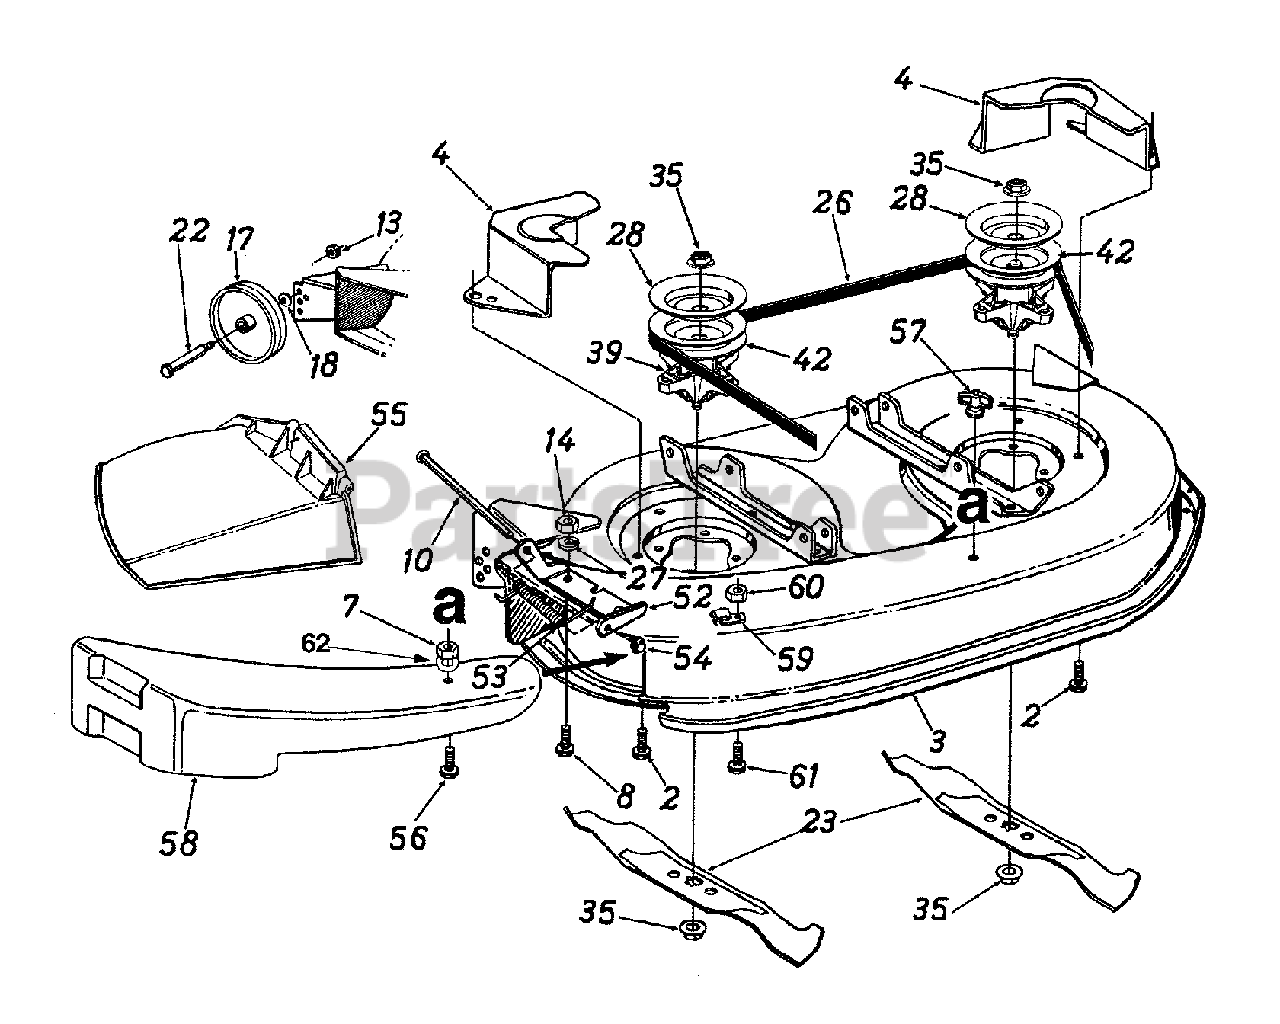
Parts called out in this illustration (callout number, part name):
2	Hex Wash. TT-Tap Scr. 5/16-18 x .75"
7	Hex Lock Nut 1/4-20 Thd.
8	Hex Bolt 1/4-20 x .62"
10	Hinge Pin
13	Hex Top Lock Nut 3/8-16 Thd.
14	Hex Nut 1/4-20 Thd. (Gr. 5)
17	Deck Wheel- 5"
18	BelLock Washer .40" I.D. x .88" O.D.
22	Shld. Bolt .498" Dia. x 1.53"
23	3 in 1 Blade
26	V-Belt
27	Washer 1/4" I.D.
28	Brake Disc
35	Hex Flange Nut 5/8-18 Thd.
39	Blade Spindle Assembly
42	5.75" Dia. Pulley
52	Hinge Mtg. Brkt.
53	Torsion Spring
54	Push Nut
55	Chute Ass'y.
56	Hex Bolt 1/4-20 x 1" Lg.
57	Wing Nut 1/4-20 Thd.
58	Mulching Plug
59	Retainer Hook Brkt.
60	Hex Flg. Nut 1/4-20 Thd.
61	Hex Bolt 1/4-20 x .62" Lg.
62	Flat Washer .28 I.D. x .74 O.D.
